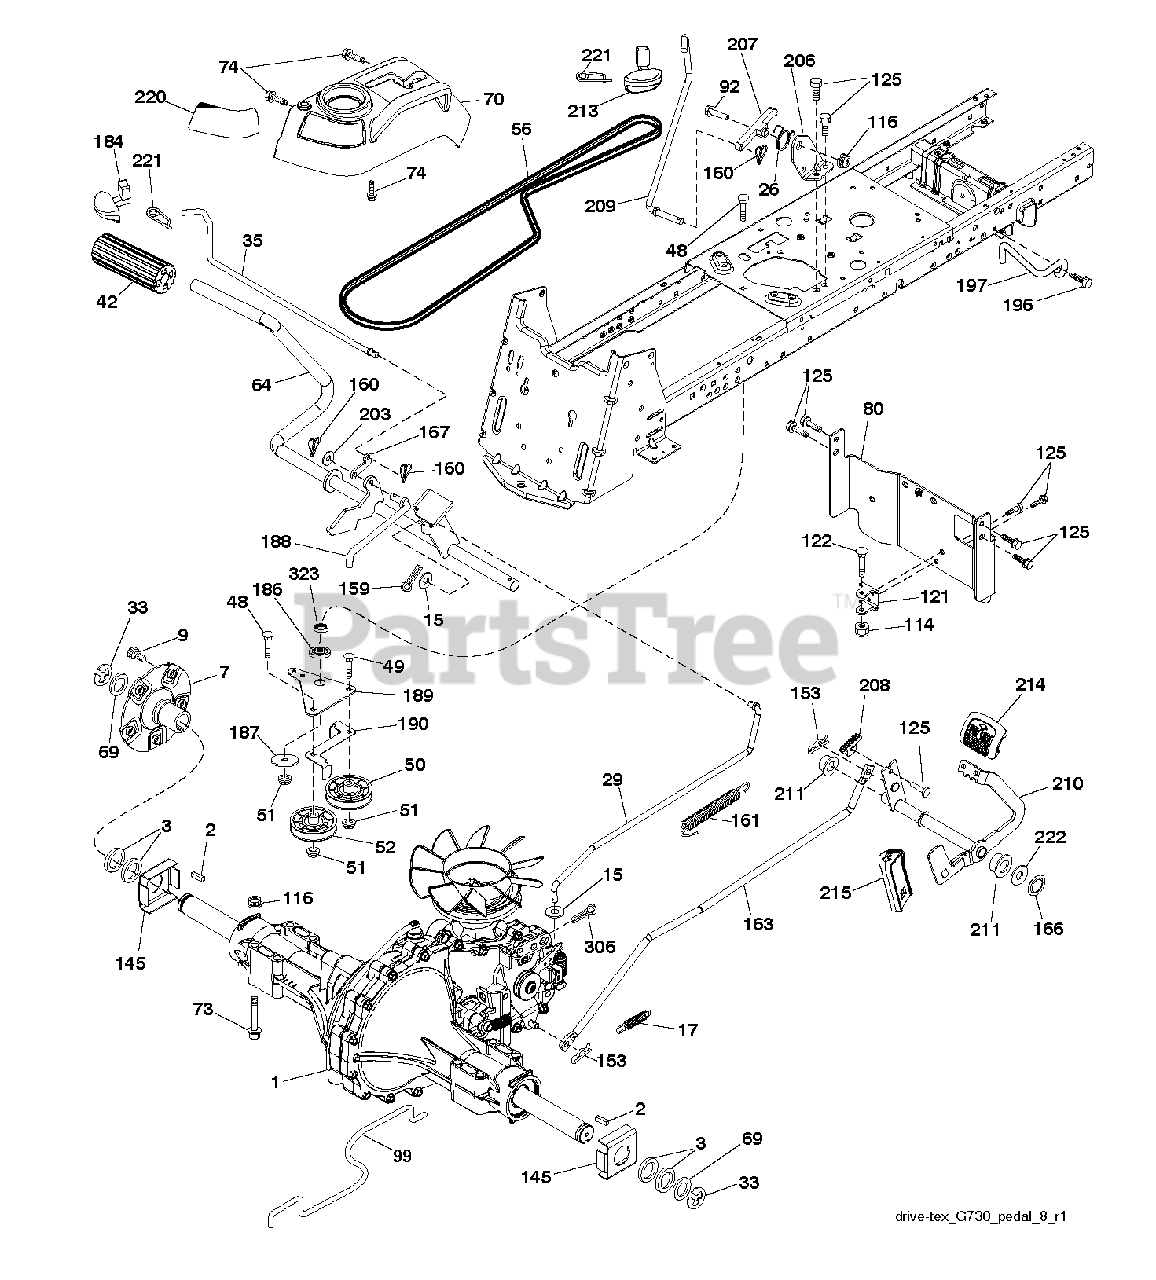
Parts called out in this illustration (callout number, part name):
2	KEY 1/4 X 2.5
7	HUB.ASM.WHEEL.REAR.23"TEX
15	WASHER
17	SPRING.BRAKE.HG3000/3500
26	SPRING.RETURN.CRUISE
33	E RING HYT
35	ROD .BRAKE. PARKING. GT. HUSQ.
42	PEDAL COVER T
48	BOLT.3/8-16X1.50
50	IDLER.FLAT.910.OFFSET
51	NUT LOCK FLG 3/8-16 UNC
52	IDLER.V-GROOVE.910.OFFSET
56	V-BELT.GROUND.DRIVE.
64	SHAFT.ASM.PEDAL.BRK.CNTR
70	CONSOLE.ASM.RH.GT.FC.HUSQ
73	BOLT HEX FLGHD 5/16-18X3 GR. 5
74	SCREW.HI-LO.CONSOLE
80	STRAP.TORQUE.YT.G700
92	BOLT
99	SPRING.BYPASS.YT.G700
114	NUT.71038.31-18.HEX.NYLOCK
116	NUT LOCK HEX FLANGE 5/16-18
121	BRACKET STRAP TORQUE
122	BOLT.5/16-18X2.5
125	SCREW
145	WASHER.AXLE.FLANGE.HG-3000
153	RETAINER M
159	COTTER PIN
160	RETAINER CLIP
161	SPRING, RETURN LT
163	ROD PEDAL CONTROL
166	NUT.PUSH.625
167	LATCH.BRAKE.SPRING
184	RB HANDLE.PARKG.BRK.HUS/PRED
186	SPACER.RETAINER
187	WASHER 12/32X2X10GA
188	RP LINK.CLUTCH.GROUND.DRIVE
189	BELLCRANK.GROUND.DRIVE.TRAPPED
190	KEEPER BELLCRANK ROUND DRIVE
196	SCREW 3/8-16X1
197	BRKT.ANIT-ROTATION.CLUTCH
203	WASHER
206	BRKT.MOUNT.LATCH.CRUIS
207	LATCH.CONTROL.CRUISE
208	GEAR.SECTOR.CONTROL.CR
209	ROD.CONTROL.CRUISE.GT.
210	ROCKER.ASM.PEDAL.CONTR
211	BEARING.NYLON
213	KNOB.CONTROL.CRUSIE.HU
214	PEDAL.FORWARD.PAD.TEX
215	PEDAL.REVERSE.TEX.GT.4
220	REFLECTOR.RH.TEX GT
221	RETAINER.SPRING.CLIP.H
222	WASHER 21/32 X 1-1/4 X 10 GA.
306	PIN COTTER
323	SLEEVE.BELLCRANK
